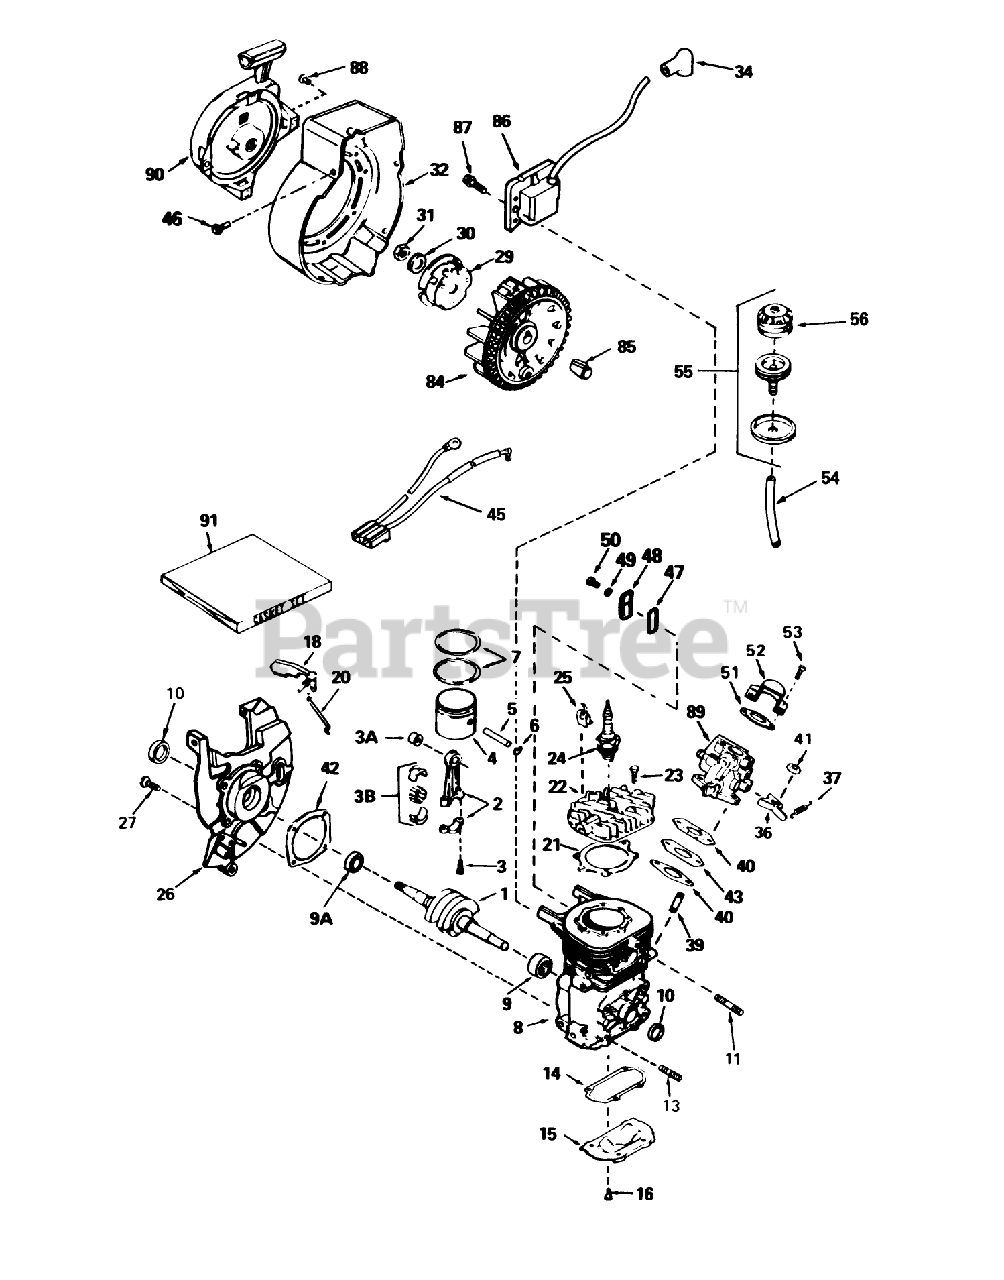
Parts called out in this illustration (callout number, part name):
1	Crankshaft
2	Rod Assy.-Connecting (Incl. Ref. #3, 3A 3B)
3	Bolt-Rod, Connecting
3A	Bearing-Cartridge
3B	Needle Bearing and Liner Set (37 Needles)
4	Piston
5	Pin-Piston
6	Ring-Retaning
7	Ring Set
8	Block Assy.-Cylinder (Order short block if replacement is required.)
9	Bearing-Cartridge
9A	Bearing-Ball
10	Seal-Oil
14	Cover
15	Plate-Cover
16	Screw (T-25, 10-24 x 1/2)
18	Vane Assy., Air
20	Link-Governor
21	Gasket, Head
22	Head-Cylinder
23	Screw (T-30, 1/4-20 x 3/4)
24	Spark Plug-Resistor (R C J 8Y)
26	Base Assy.-Blower Housing (Incl. Ref. #10)
27	Screw (1/4-20x19/32)
29	Cup-Starter
30	Washer-Belleville
31	Nut-Flywheel
32	Housing-Blower
34	Cover-Spark Plug
36	Lever-Adjusting, Rpm
37	Spring-Governor
40	Gasket-Carburetor
41	Locknut
42	Gasket, Shroud Base
43	Spacer
45	Harness-Wire
46	Screw-Hex, Hd.
47	Gasket-Cover
48	Comp. Release Cover
49	Washer
50	Screw (T-25, 10-24 x 1/2)
51	Gasket
52	Baffle-Carburetor
53	Screw
54	Line-Primer
55	Primer Assy.
56	Bulb-Primer
84	Flywheel
85	Blade (20 inch)
86	Solid State
87	Screw
88	Rivet-Pop (3/16" Dia.) (Can be purchased locally)
89	Carburetor (Incl. Ref. #40)
90	Starter-Rewind
91	Gasket Set
